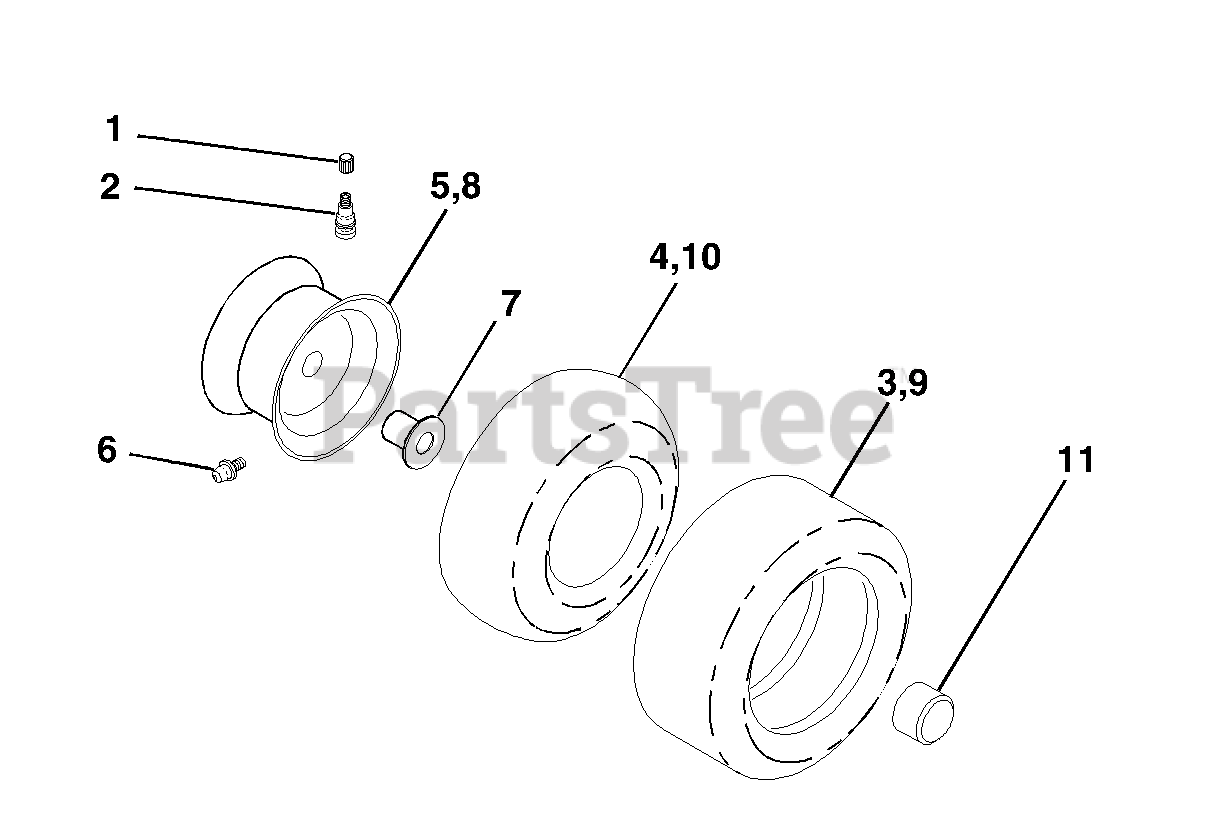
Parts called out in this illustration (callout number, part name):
1	Cap Valve Tire
2	Stem Valve
3	Tire F T 15 X 6 0 - 6 Service
4	Tube Front
5	Rim Asm 6" front Service
6	Fitting Grease
7	Bearing Flange
8	Rim Asm 8" rear Service
9	Tire R T 20x10-8 Service
10	Tube Rear
11	Cap Axle Blk 1 50 X 1 00
